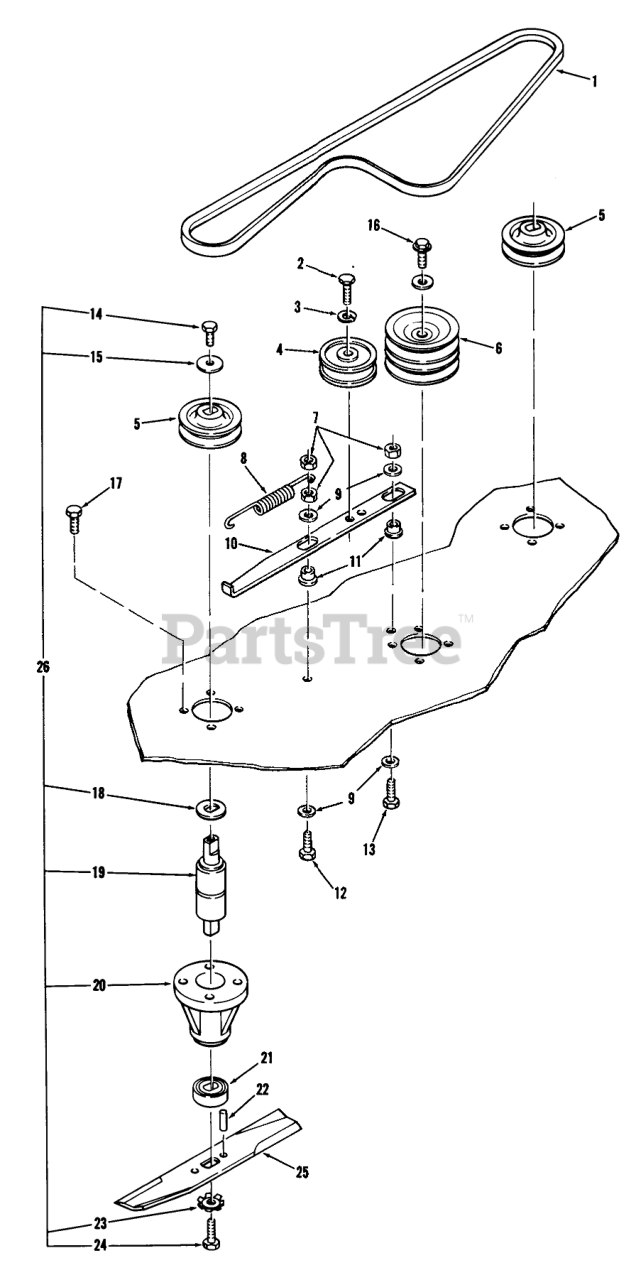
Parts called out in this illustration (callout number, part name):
1	V-BELT
2	BOLT HEX SPECIAL
3	LOCKWASHER
4	Idler Pulley
5	Pulley
6	Pulley-Center Drive
7	Nut
8	SPRING-EXTENSION
9	WASHER
10	BAR-IDLER SUPPORT
11	Bushing/Spacer
12	Bolt
13	Bolt
14	Bolt
15	WASHER
16	Bolt-Lock 3/8-16 x 7/8
17	Bolt
18	WASHER-DOUBLE D
19	BEARING
20	HOUSING-BEARING B
21	Cup-Spindle
22	SPIROL ROLL PIN
23	WASHER
24	Bolt
25	BLADE KIT 36 LF REAR
25	BLADE KIT
26	S/A SPINDLE ASSY
